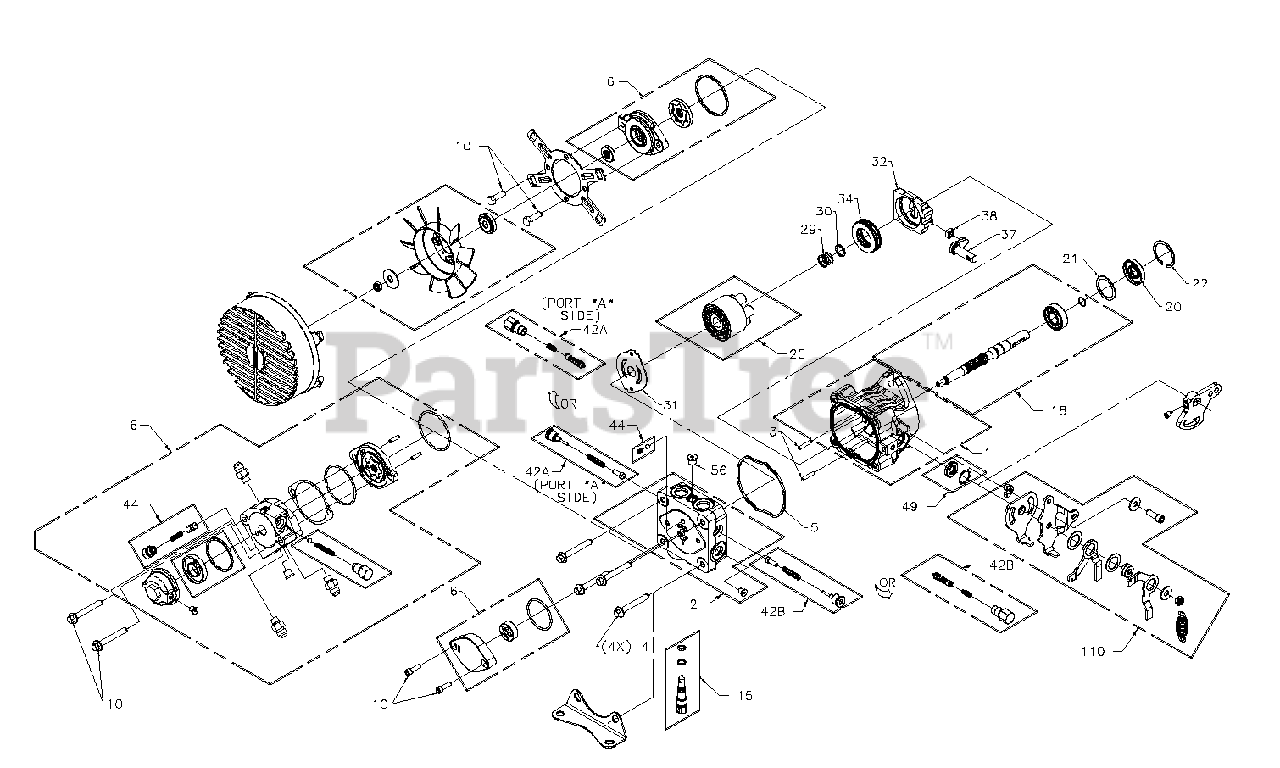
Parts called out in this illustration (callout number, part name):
1	Kit, Housing
2	Kit, End Cap w/Poppets
3	Straight Headless Pin
4	Hex, Flange Bolt M8-1.25 x 60mm
6	Kit, Chg Pump
10	Cap Screw 5/16-18
15	Kit, Bypass
18	Kit, Pump Shaft (15mm Straight Keyed, Thru)
20	Lip Seal 17 x 40 x 7 PTC
21	Spacer
22	Retaining Ring
25	Cylinder Block Kit
29	Block Spring
30	Block Thrust Washer
31	Valve Plate
32	Swashplate
34	Ball Thrust Bearing
37	Arm, Trunnion, Tapered Square
38	Slot Guide
42	Kit, Shock Valve (200 Bar .031 Orifice)
44	Kit, Charge Relief Valve
49	Trunnion Seal - Retainer Kit
56	Plug, Straight Thread
110	Kit, Return
NS	Overhaul Seal Kit
